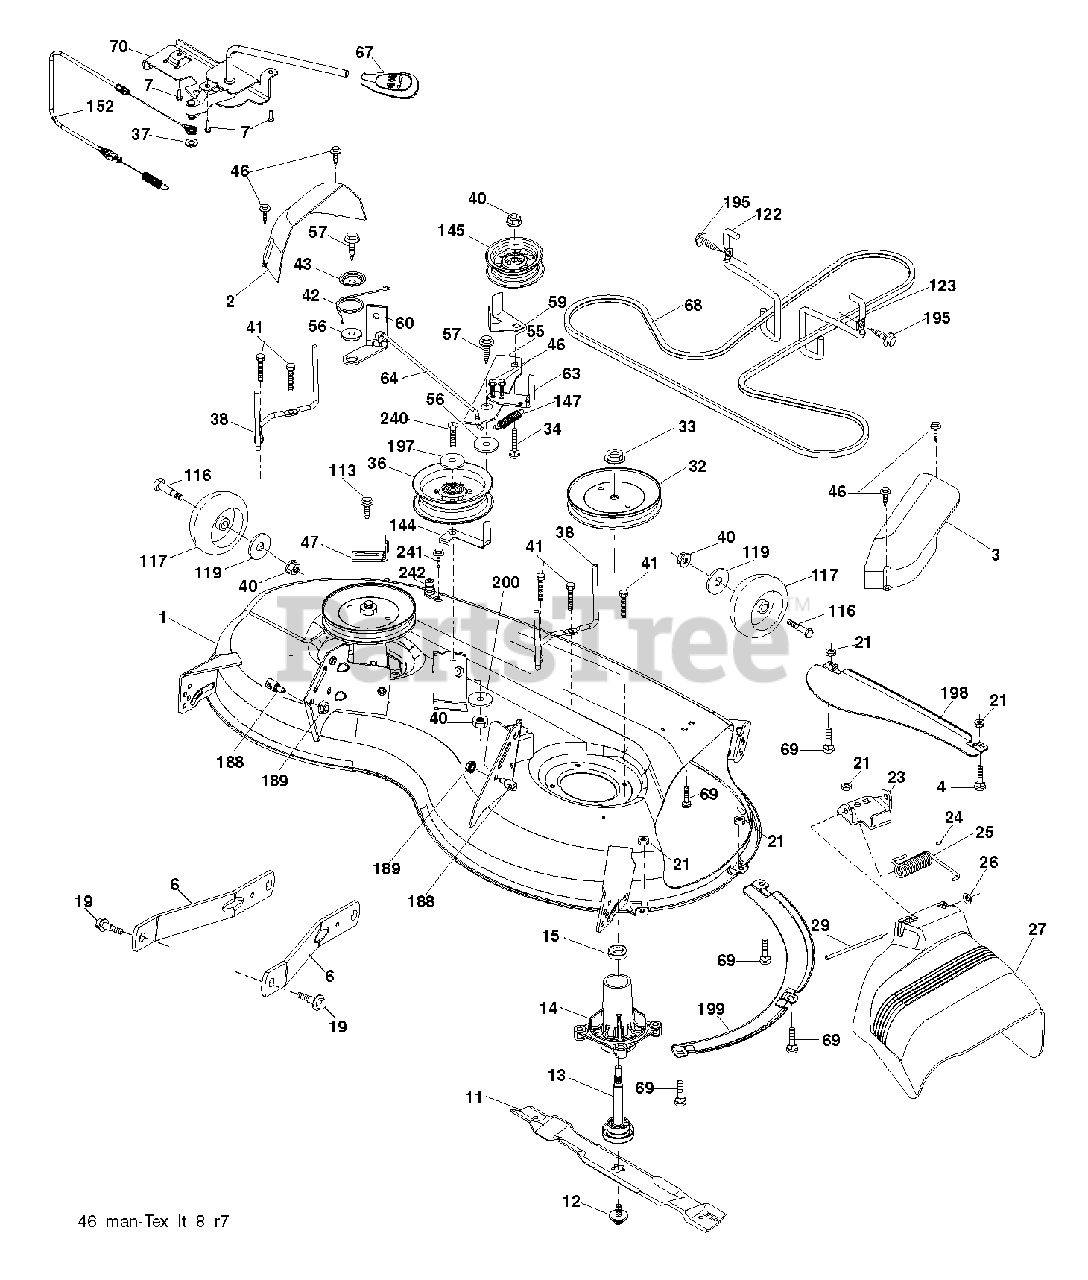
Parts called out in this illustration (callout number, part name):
2	COVER.MANDREL.LH.46"
3	COVER.MANDREL.RH.46"
4	BOLT
6	ARM.SUSPENSION.MOWER.R
7	SCREW.#10 X 0.750.BOS (2 2)
11	BLADE.MOWER.46".HI.LIFT
12	Screw, 7/16 X 20 X 1"
13	SHAFT.ASM.MDRL.N/GREASE.38
14	HOUSING.MANDREL.4PT.
19	BOLT.SHOULDER
21	LOCKNUT
23	BRKT.DEFLECTOR.38"2005+
24	CAP-SLEEVE LT
25	SPRING.TORSION.DEFLECT
26	NUT PUSH M
27	SHIELD.DEFLECTOR.MOWER.46"BLAC
29	ROD.HINGE
32	PULLEY.MANDREL.5.438.PD
33	NUT.FLANGE.LOCK.TOP
34	BOLT.3/8-16X1.50
36	PULLEY.IDLER.2006
38	KEEPER.BELT.MANDREL.PULLEY
40	NUT LOCK FLG 3/8-16 UNC
41	Hex Washer Head Bolt, .313-18 X 1.19
42	SPRING.TORSION.BRAKE
43	SRPING.TORSION.RETAINE
46	SCREW.1/4-20X5/8
47	BRKT.CLUTCH.CABLE
55	IDLER.ARM
56	SPACER.RETAINER
57	SCREW 3/8-16X1
59	GUARD, BELT
60	ARM BRAKE MOWER RH 38"
64	LINKAGE BRAKE
67	HANDLE.CLUTCH.CABLE.LT
68	V-BELT
69	BOLT
70	CLUTCH.ASM.MANUAL.YT.PREDATORQ
113	BOLT.5/16HEX.WHS.HD
116	BOLT M
117	WHEEL.GAGE.HALF.SPOKED
119	WASHER
122	KEEPER BELT ENGINE LH
123	KEEPER BELT RH
144	KEEPER.BELT.MOWER
145	PULLEY.IDLER.48"PRIMARY
147	RETURN SPRING
152	CABLE.MECHANICAL.CLUTCH
188	STUD.FASTNER.W/ANTI-ROTATE
189	NUT LOCK HEX FLANGE 5/16-18
195	SCREW, 3/8-16X3/4
197	WASHER
198	BAFFLE CENTER FRONT
199	BAFFLE FRONT RH
200	WASHER.13/32 X 1 X 1/2.11GUARD
240	BOLT-HEX EAK
241	SCREW.TT.#10-32X.5.3/8.FLANGE
242	PORT.WASHOUT
